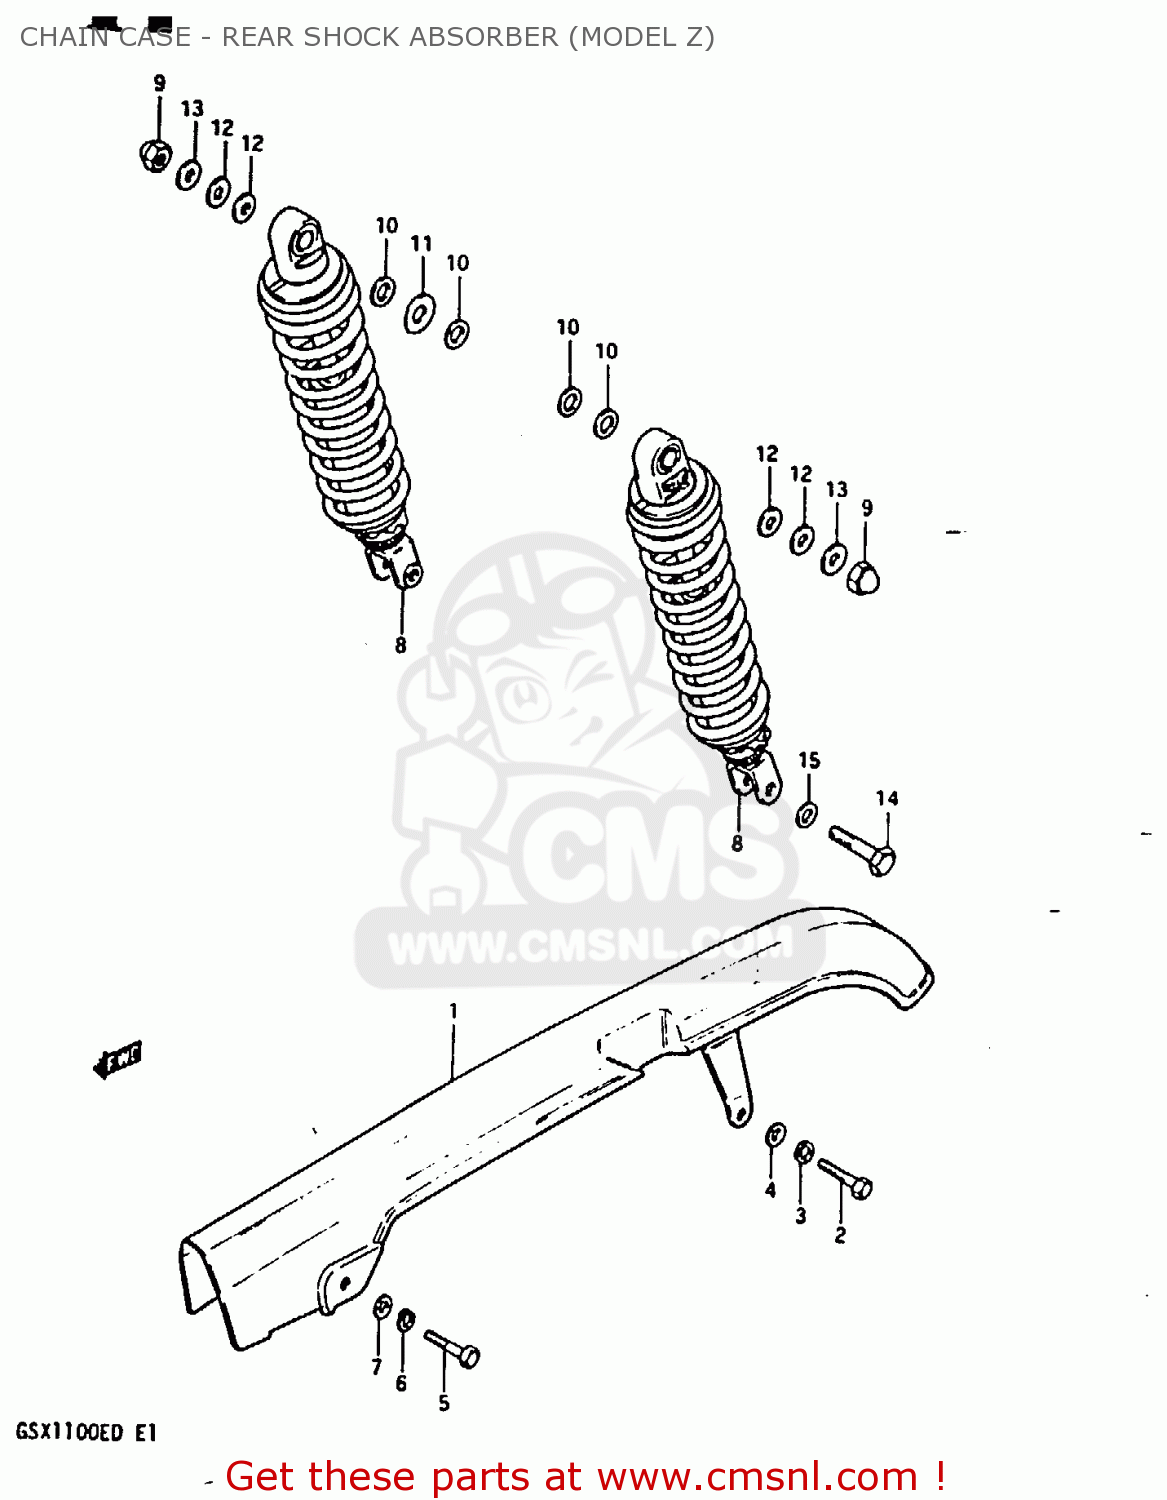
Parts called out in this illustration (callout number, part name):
1	CASE,CHAIN
2	BOLT
3	LOCK WASHER
4	WASHER
5	BOLT
6	LOCK WASHER
7	WASHER
8	SHOCK ABSORBER
9	NUT, LOWER LH
10	WASHER
11	WASHER (12.5X24X3.2)
12	WASHER
13	WASHER(10.5X24X3.2)
14	BOLT(10X36)
15	WASHER
